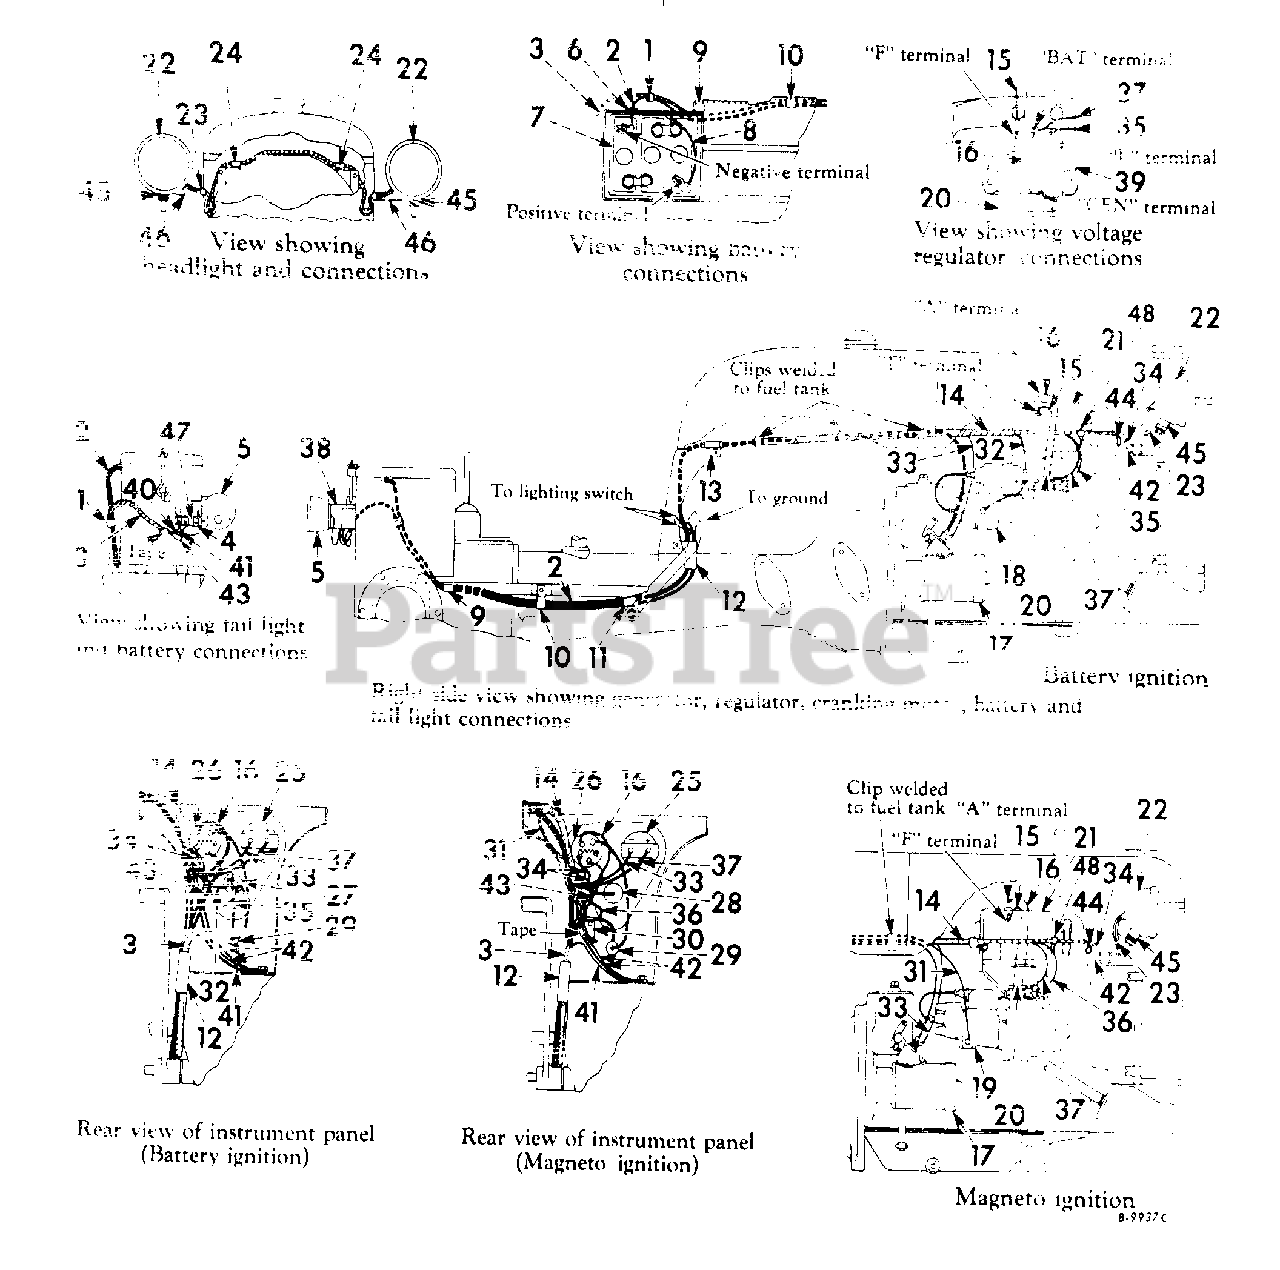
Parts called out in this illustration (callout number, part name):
1	STRAP, WRAPPING CABLE
2	CABLE, BATTERY TO CRANKING MOTOR
3	HARNESS ASSY, REAR LIGHT CABLE
4	BRACKET, JUNCTION BLOCK MOUNTING
5	LIGHT ASSY, TAIL
6	GROMMET, BATTERY BOX
7	BATTERY - 6 VOLT
8	CABLE, BATTERY TO GROUND
9	CLIP, CABLE ANGLE - 1/2 IN. OPENING
10	CLIP, THIRD BOLT FROM REAR - 7/8 IN. OPENING
11	STRAP, CABLE WRAPPING
12	CLIP, INSIDE RIGHT SIDE FUEL TANK SUPPORT
13	CLIP CABLE HARNESS
14	HARNESS ASSY, MAIN CABLE
15	CABLE, GENERATOR
16	CABLE, GENERATOR
17	MOTOR ASSY, CRANKING
18	BATTERY IGNITION UNIT
19	MAGNETO ASSY
20	REGULATOR ASSY, VOLTAGE
21	GENERATOR ASSY
22	LIGHT ASSY HEAD
23	GROMMET RUBBER NO. 6
24	CLIP HEAD LIGHT CABLE HARNESS
25	INDICATOR ASSY CHARGE
26	SWITCH ASSY LIGHTING
27	SWITCH ASSY, BATTERY IGNITION
28	SWITCH ASSY, MAGNETO IGNITION
29	HOUSING, FUSE W/KNOB IH-356445-R91
30	BLOCK ASSY, MAGNETO IGNITION JUNCTION
31	CABLE, MAGNETO IGNITION SWITCH TO MAGNETO
32	CABLE, BATTERY IGNITION SWITCH TO COIL, ORANGE
33	CABLE, CHARGE INDICATOR TO STARTING SWITCH, BROWN
34	CABLE, SWITCH TO HEAD LIGHT
35	CABLE, REGULATOR -L- TERMINAL TO SWITCH, LIGHT GREEN
36	CABLE, REGULATOR -L- TERMINAL TO JUNCTION BLOCK
37	CABLE, REGULATOR -BAT- TERMINAL TO CHARGE INDICATOR, GRAY
38	BRACKET, TAIL LIGHT
39	BRACKET, VOLTAGE REGULATOR MOUNTING
40	CABLE, LIGHTING SWITCH TO JUNCTION
41	CABLE, JUNCTION BLOCK TO GROUND, PINK
42	CABLE, HEAD LIGHT TO GROUND, PINK
43	CABLE, TO LIGHTING SWITCH - RL - TERMINAL, RED
44	CABLE, HORN TO LINE CONNECTOR, DARK GREEN
45	SPACER, HEAD LIGHT
46	POST, HEAD LIGHT
47	BLOCK ASSY TAIL LIGHT JUNCTION
48	CLIP CABLE HARNESS
